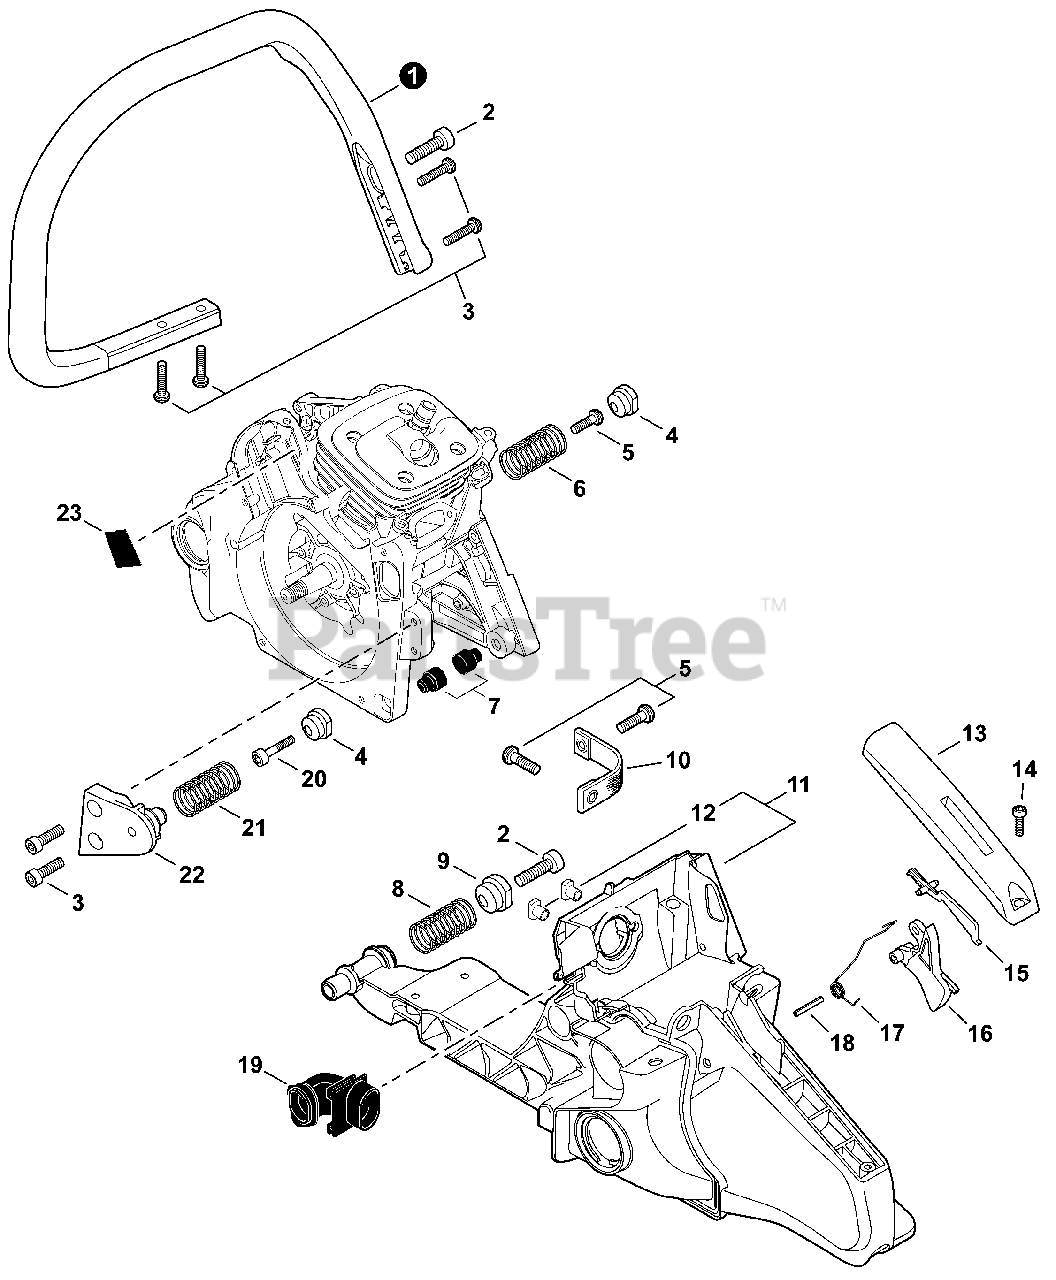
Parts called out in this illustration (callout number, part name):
1	HANDLE, FRONT
2	BOLT, TORX 6×20
3	BOLT, TORX 5×20
4	HOLDER, SPRING 14.4
5	BOLT, TORX 5×16
6	SPRING, COMPRESSION 17×38.4×2.6
7	CUSHION
8	SPRING, COMPRESSION 20×40×3.3
9	HOLDER, SPRING 17
10	STRAP, SAFETY
11	HANDLE, REAR
13	COVER, HANDLE
14	BOLT, TORX 4×12
15	LEVER, THROTTLE LOCKOUT
16	TRIGGER, THROTTLE
17	SPRING, TORSION
18	PIN, SPRING 4×25 SUS
19	PIPE, AIR INTAKE
20	BOLT, TORX 5×25
21	SPRING, COMPRESSION 17×36.7×2.6
22	HOLDER, SPRING
23	CUSHION
